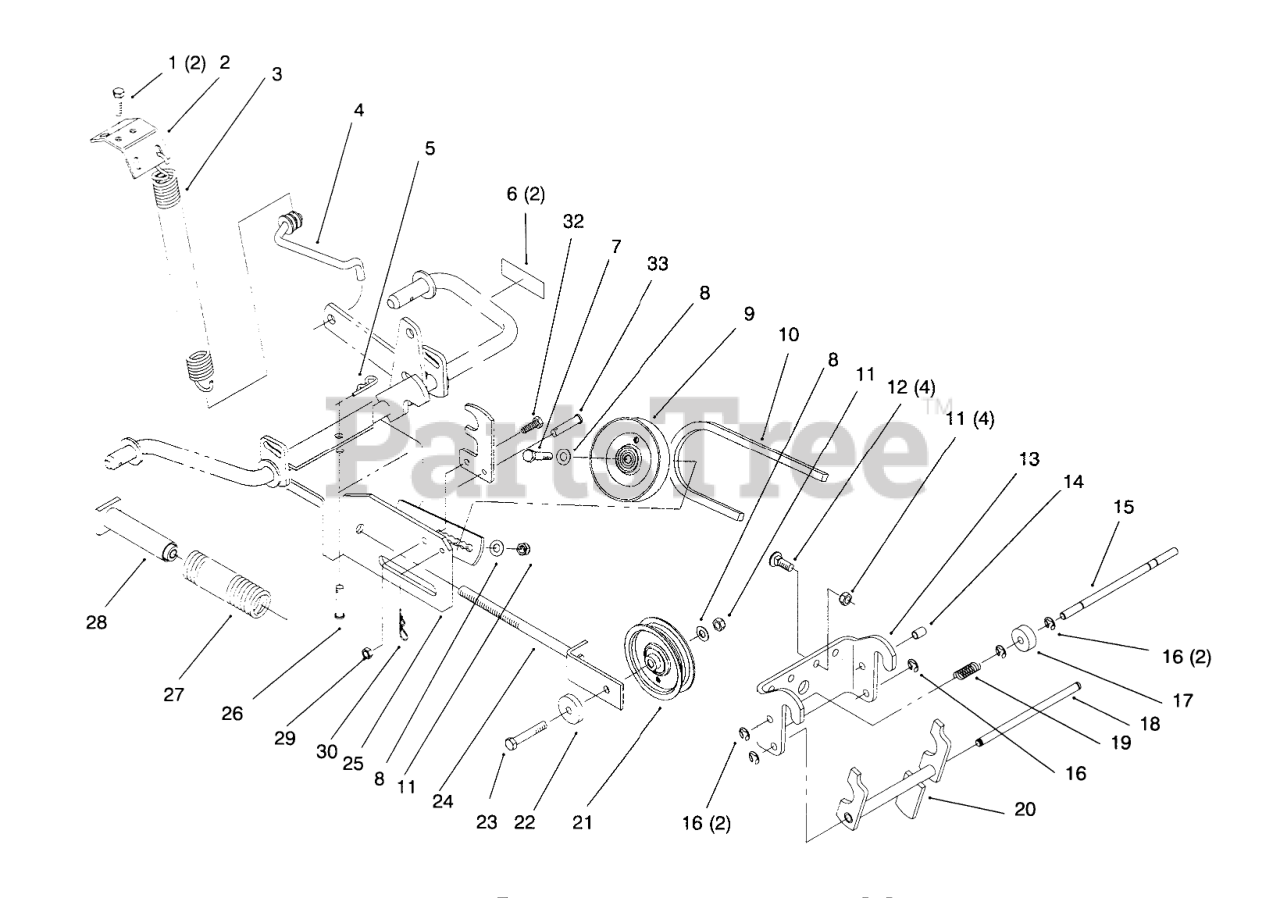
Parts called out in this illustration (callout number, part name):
1	SCREW-HH
2	BRACKET
3	SPRING-EXTENSION
4	SPRING ROD
5	PIN-HAIR
6	DECAL-WARNING
7	SCREW-HH
8	WASHER-FLAT
9	PULLEY-IDLER
10	Belt
11	NUT-LOCK, NI
12	SCREW-CARR
13	HITCH-FRONT
14	CAP-ROD, PLUNGER
15	ROD-LOCK
16	RING-RETAINING
18	ROD-LATCH PIVOT
19	SPRING
20	LATCH
21	PULLEY-IDLER, FLAT
22	BUSHING
23	SCREW-HH
24	IDLER-SLIDE W.A.
25	BRACKET IDLER W.A.BLACK
26	Clevis Pin
27	SPRING-COMPRESSION
28	SPRING-TENSIONER
29	NUT-LOCK, NI
30	PIN-HAIR
31	Catch-Idler Support
32	SCREW-HH
33	PIN-CLEVIS
